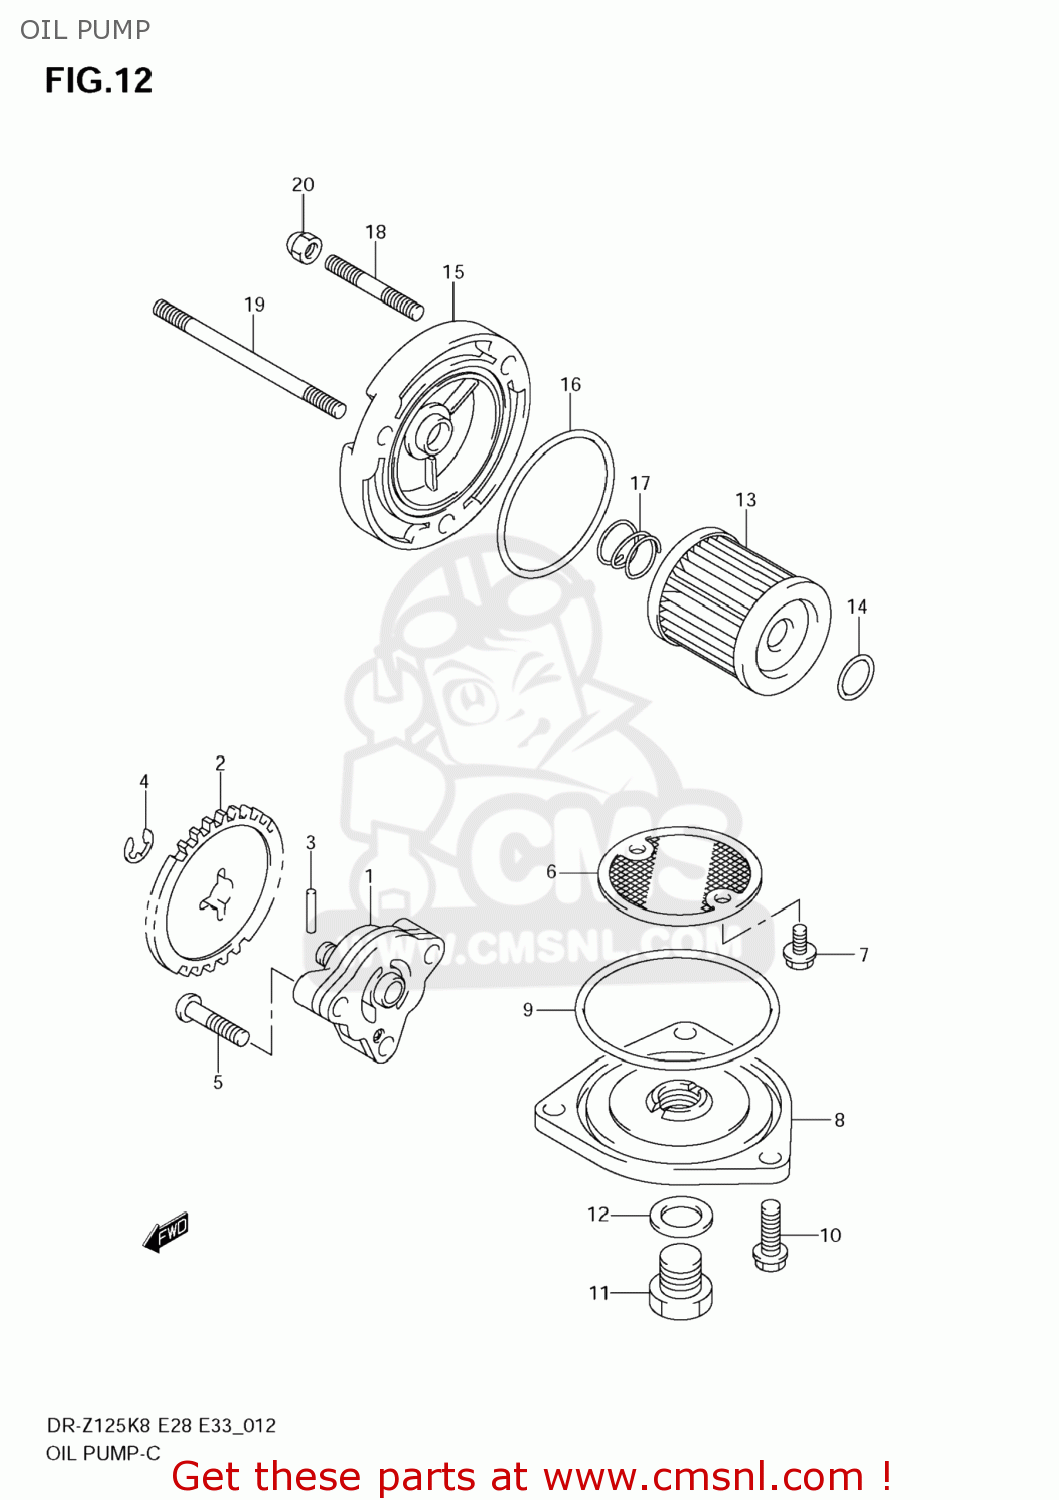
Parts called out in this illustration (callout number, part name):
1	PUMP ASSY,ENGINE OIL
2	GEAR,OIL PUMP DRIVEN
3	PIN(2.5X11.8)
4	E RING
5	SCREW
6	STRAINER,ENGINE OIL
7	SCREW
8	CAP,OIL STRAINER
9	O RING(D:2.4,ID:60.5)
10	BOLT
11	PLUG(14X12)
12	GASKET(13.8X18.8X4.8) (NAS)
13	FILTER ASSY,ENGINE OIL
14	O RING(D:1.9,ID:13)
15	CAP,OIL FILTER
16	O RING(D:2.4,ID:52.6)
17	SPRING
18	BOLT,STUD
19	BOLT,STUD
20	NUT
